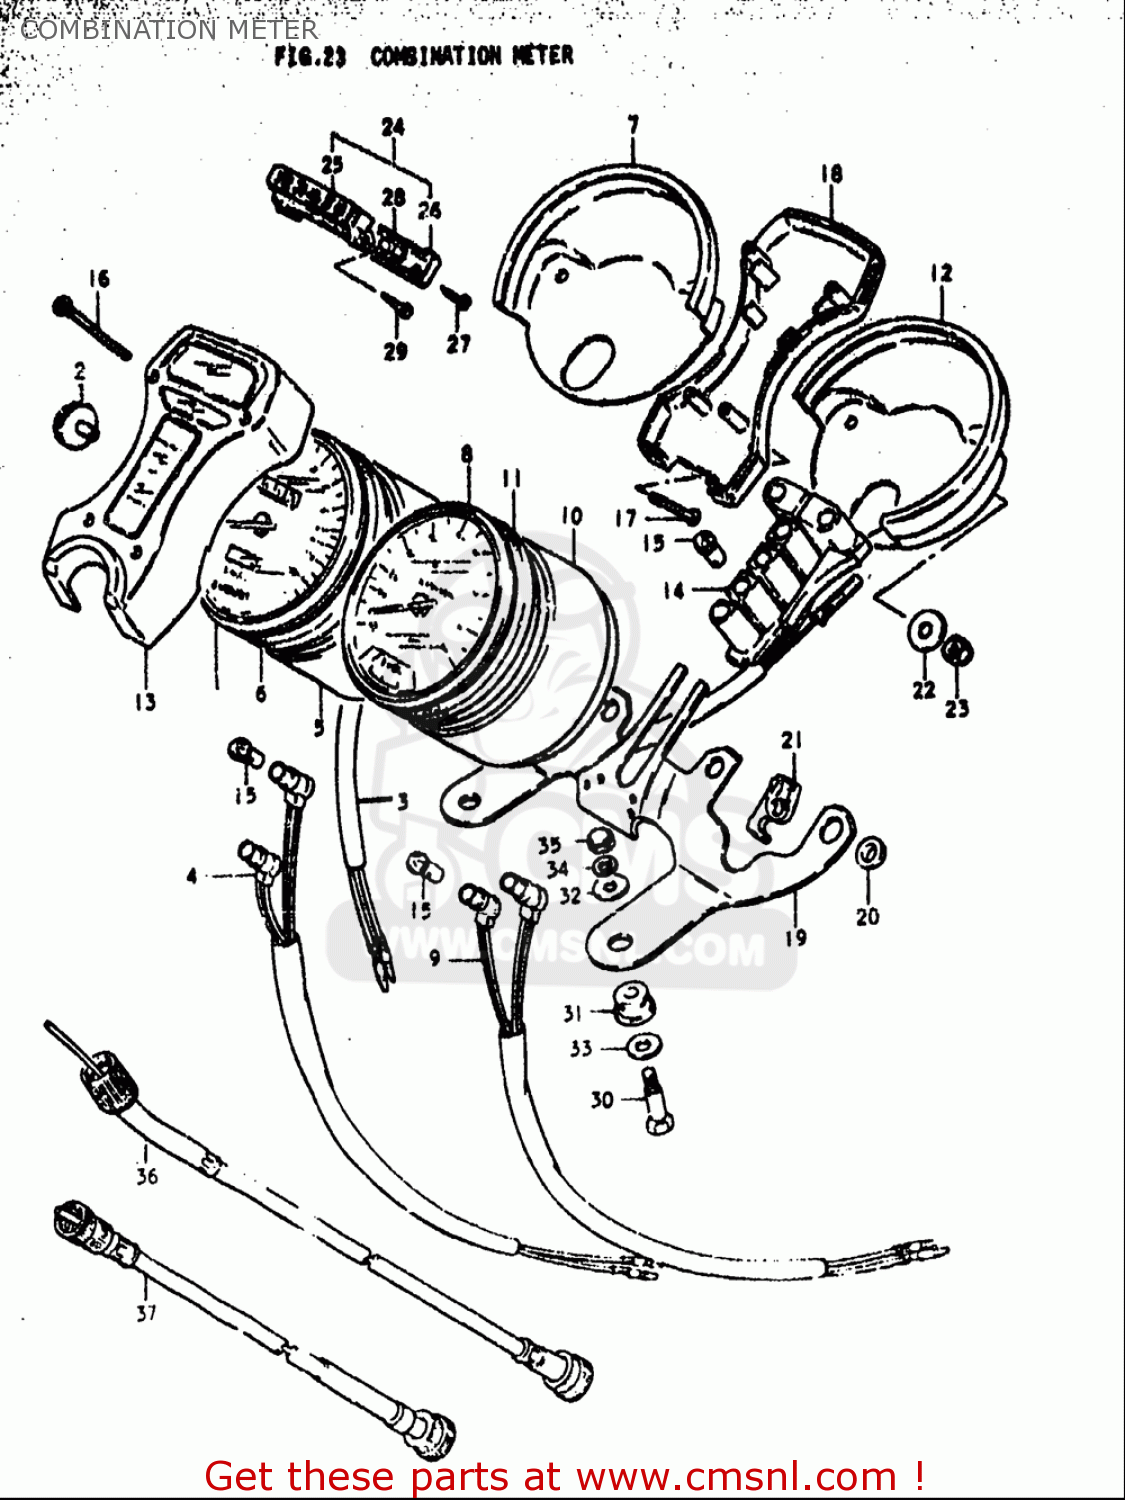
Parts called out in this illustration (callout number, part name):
15	BULB(12V3.4W,STANLEY,A72A)
16	SCREW
17	SCREW
20	CUSHION,METER (A)
22	WASHER(5.5X16X1.2)
23	NUT
26	COVER,LWR
27	SCREW
28	BULB(14V1.12W)
30	BOLT(8X31)
31	CUSHION,METER BRACKET
32	WASHER(8.5X23X1.2)
33	WASHER(10.5X28X1.6)
34	WASHER,LOCK
35	NUT
37	CABLE ASSY,TACHOMETER
